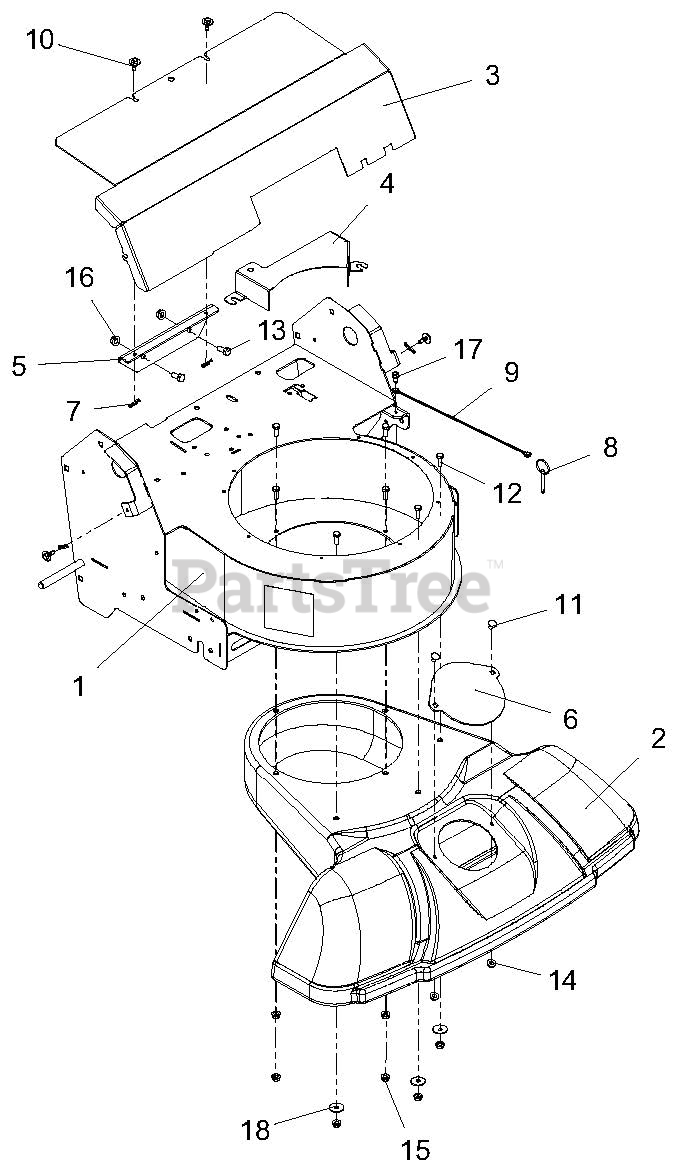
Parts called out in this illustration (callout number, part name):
1	WLDMT, FRAME - APV
2	INLET, UPPER
3	GUARD, TRANS - APV
4	GUARD, BELT - APV
5	BRKT, SUPPORT - TRANS GUARD
6	COVER, HOSE INLET - BLACK
7	PIN-HAIR, ENDRIES #25 YWZC
8	PIN, RING DETENT .25 x 1.25
10	SCR, TAP .25-20 x .5 CAPTIVE
11	BLT-RDHDSQSHNK .25-20 x .50 YWZC
12	BLT-HEX .25-20 x .75 GR5 YWZC
13	BLT-HEX .31-18 x .75 GR5 YWZC
14	NUT, LK-CTR-FLG .25-20 YWZC
15	NUT, LK-TOP-FLG .25-20 YWZC
16	NUT, LK-TOP-FLG .312-18 YWZC
17	SCR-TAP .25-20 x .50 HWH TR YWZ
18	WSHR-FL-STL .281 x 1.000 x .063 YWZC
